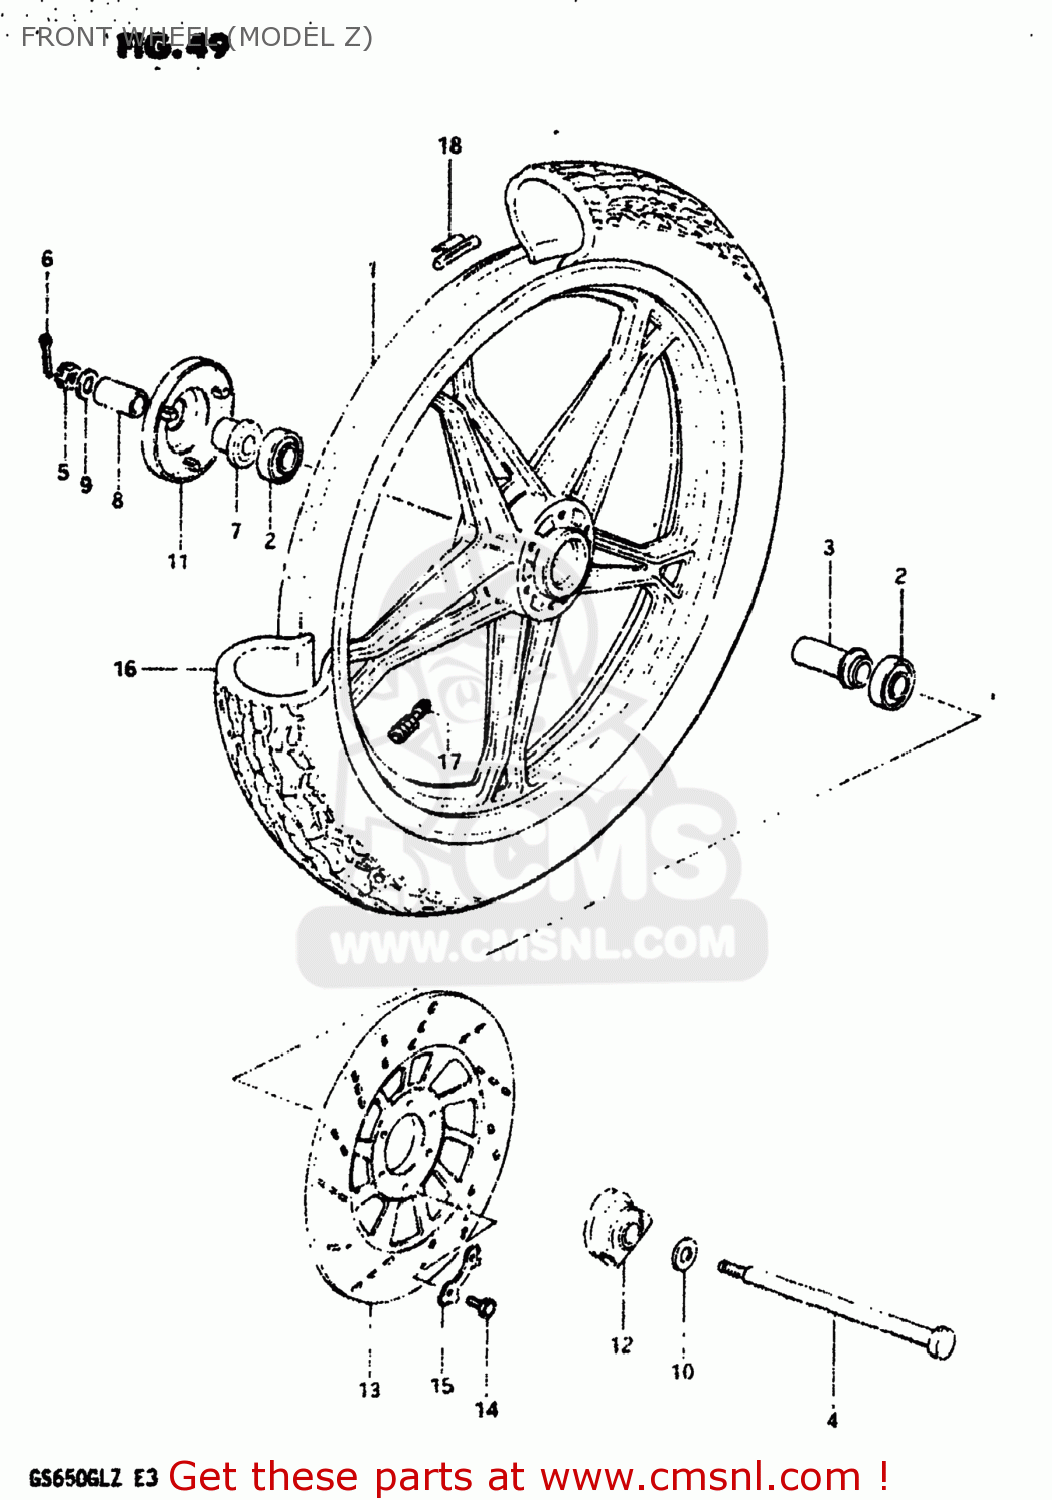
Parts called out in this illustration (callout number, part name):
1	CASTING WHEEL,FRONT 1.85
2	BEARING
3	SPACER,FR HUB BEARING
4	AXLE,FR
5	NUT 12MM
6	COTTER PIN
7	SPACER,FR AXLE,R
8	SPACER
9	WASHER
10	WASHER(15.5X26X2.3)
11	COVER,FR HUB,R
12	BOX ASSY,SPEEDOMETER GEAR
13	DISC,BRAKE
14	BOLT(8X25)
15	WASHER
16	TIRE,FRONT
17	VALVE ASSEMBLY,WHEEL RIM,J
18	BALANCER,WHEEL
